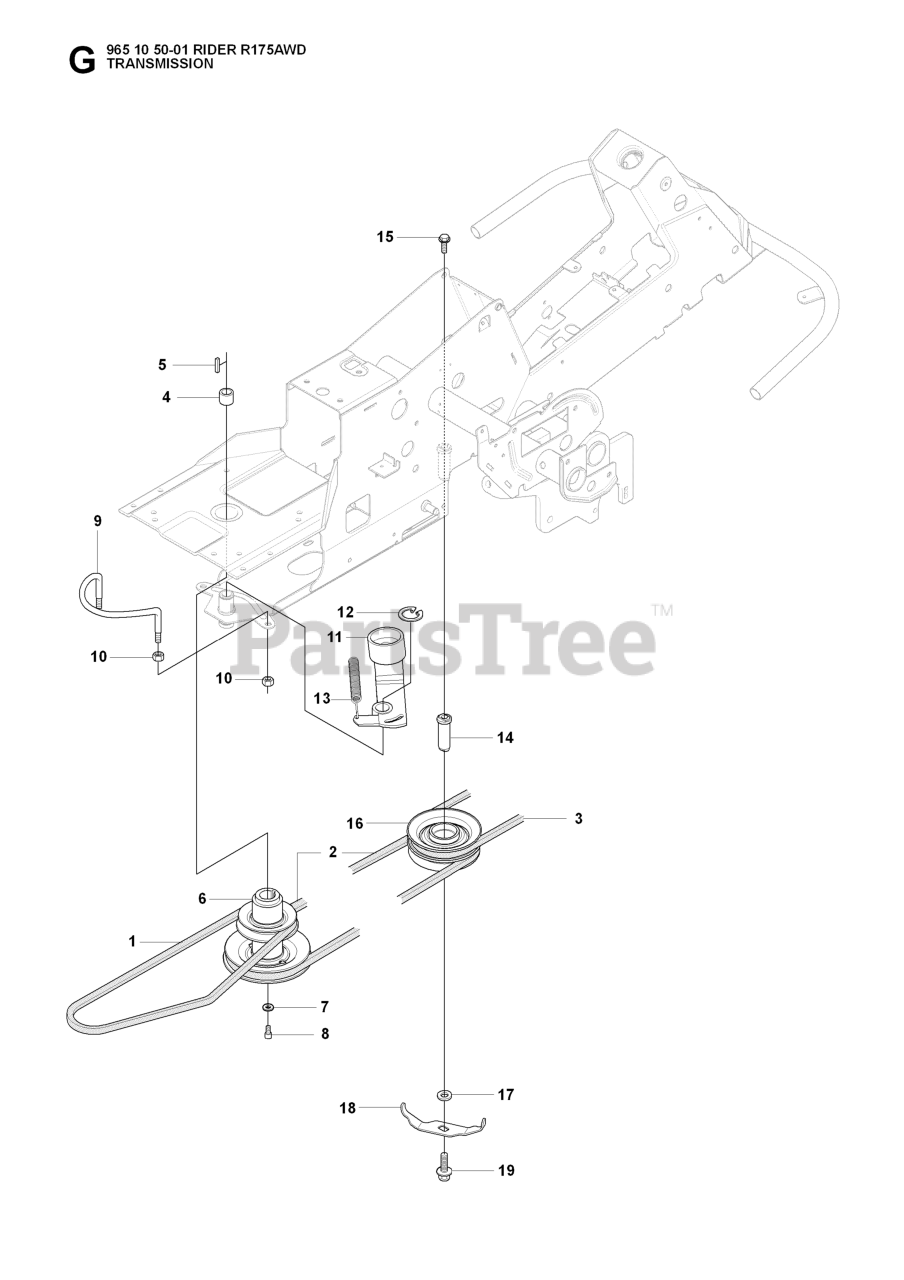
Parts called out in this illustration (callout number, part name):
1	BELT
2	BELT
9	BELT GUIDE
10	NUT
12	RETAINING RING SGA 25
14	SHAFT
18	BELT GUIDE
19	BOLT
